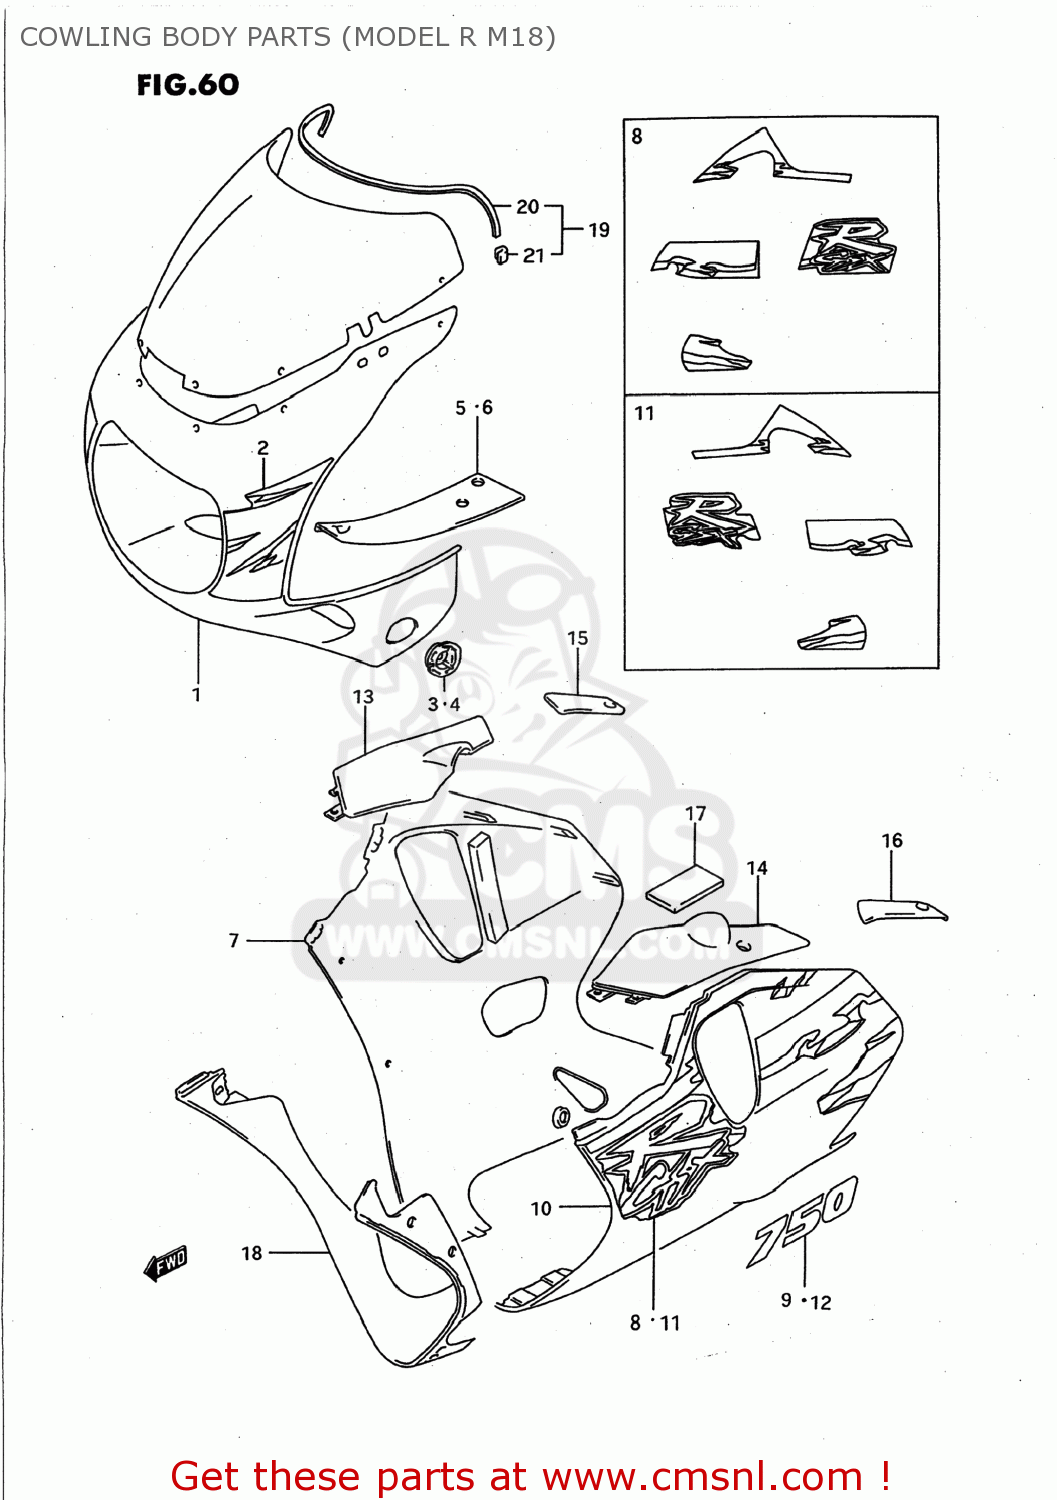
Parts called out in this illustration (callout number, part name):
1	COWLING ASSY,BODY
2	TAPE SET,COWLING BODY
3	PLATE,TURN SIGNAL,RIGHT
4	PLATE,TURN SIGNAL,LEFT
5	PANEL,COWLING,UPPER,RIGHT
6	PANEL,UPPER,LEFT
7	COWLING ASSEMBLY,UNDER,RIGHT
8	TAPE SET,COWL UNDER,R
9	EMBLEM,COWLING UNDER
10	COWLING ASSY,UNDER,L
11	TAPE SET,COWL UNDER,L
12	EMBLEM,COWLING UNDER
13	PANEL,LWR FR,R
14	PANEL,LWR FR,L
15	PANEL,LWR RR,R
16	PANEL,LWR RR,L
17	CUSHION,PANEL
18	COWLING,UNDER CTR
19	WINDSCREEN SET
20	MOLDING WINDSCREEN
21	CLIP,WINDSCREEN MOLDING
